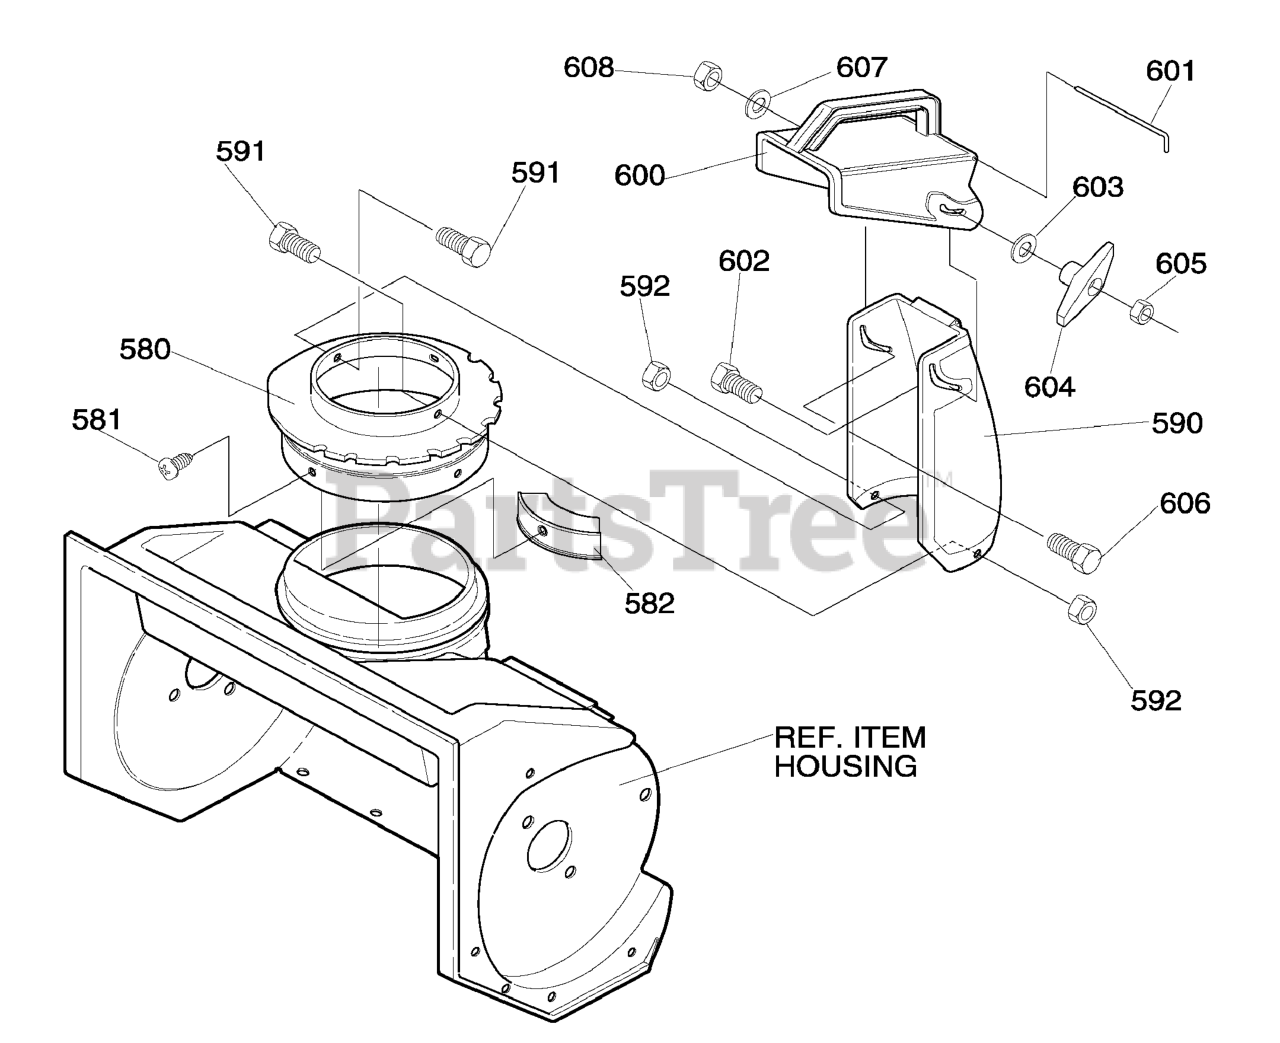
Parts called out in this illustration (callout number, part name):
580	RING, CHUTE
581	SCREW, 1/4-20 x .50
582	GUIDE, CHUTE
590	LOWER CHUTE
591	SCREW, 1/4-20 x .50
592	NUT, 1/4-20
600	UPPER CHUTE
601	WIRE HINGE
602	BOLT, 5/16-18 x 1.25
603	FLATWASHER
604	T KNOB
605	NUT, 5/16-18
606	SCREW, 5/16-18 x 0.75 SL
607	FLATWASHER
608	NUT, 5/16-18
